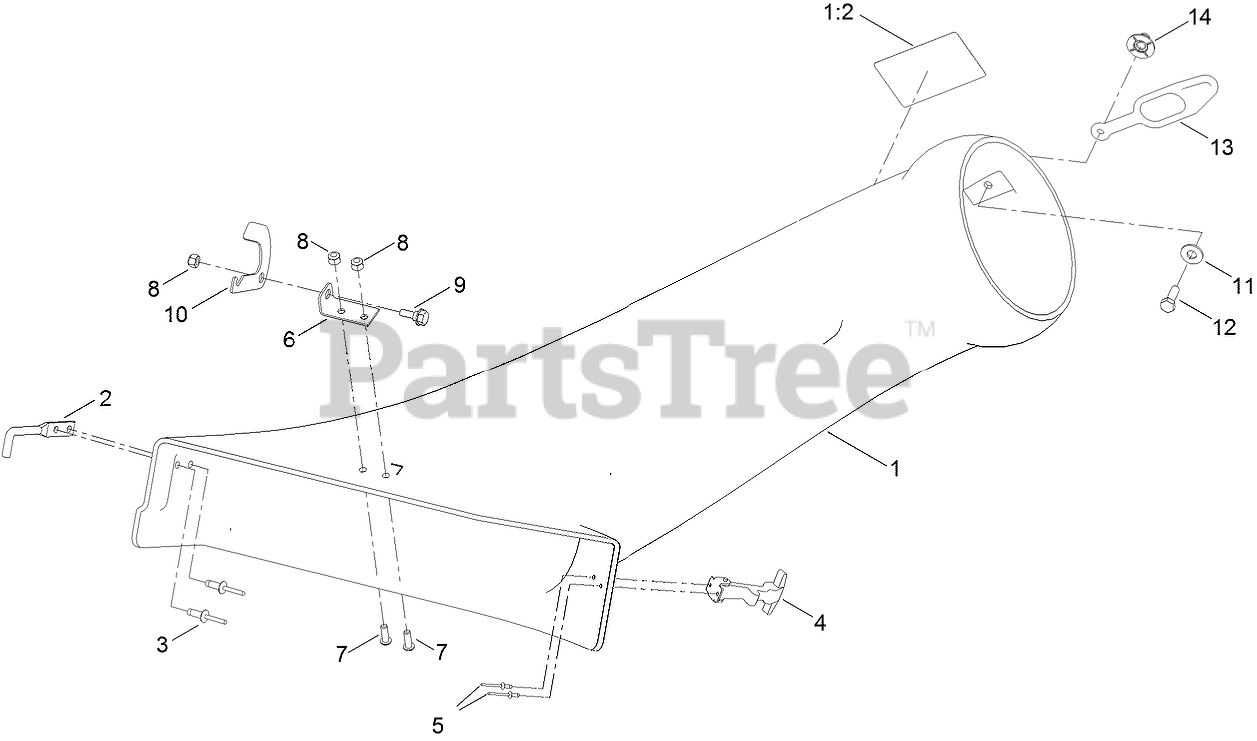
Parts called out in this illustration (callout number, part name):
1	42 In Bagger Boot ASM
1:2	DECAL-DANGER
2	HOOK-BOOT
3	RIVET-BLIND
4	HANDLE ASM
5	RIVET-POP
6	Plate-Pivot, Cz
7	SCREW-HSBH
8	NUT-HEX
9	SCREW-SHOULDER, HHF
10	Plate-Latch
11	WASHER-FLAT
12	SCREW-HH
13	RETAINER-DUCT
14	NUT-IMPELLER
